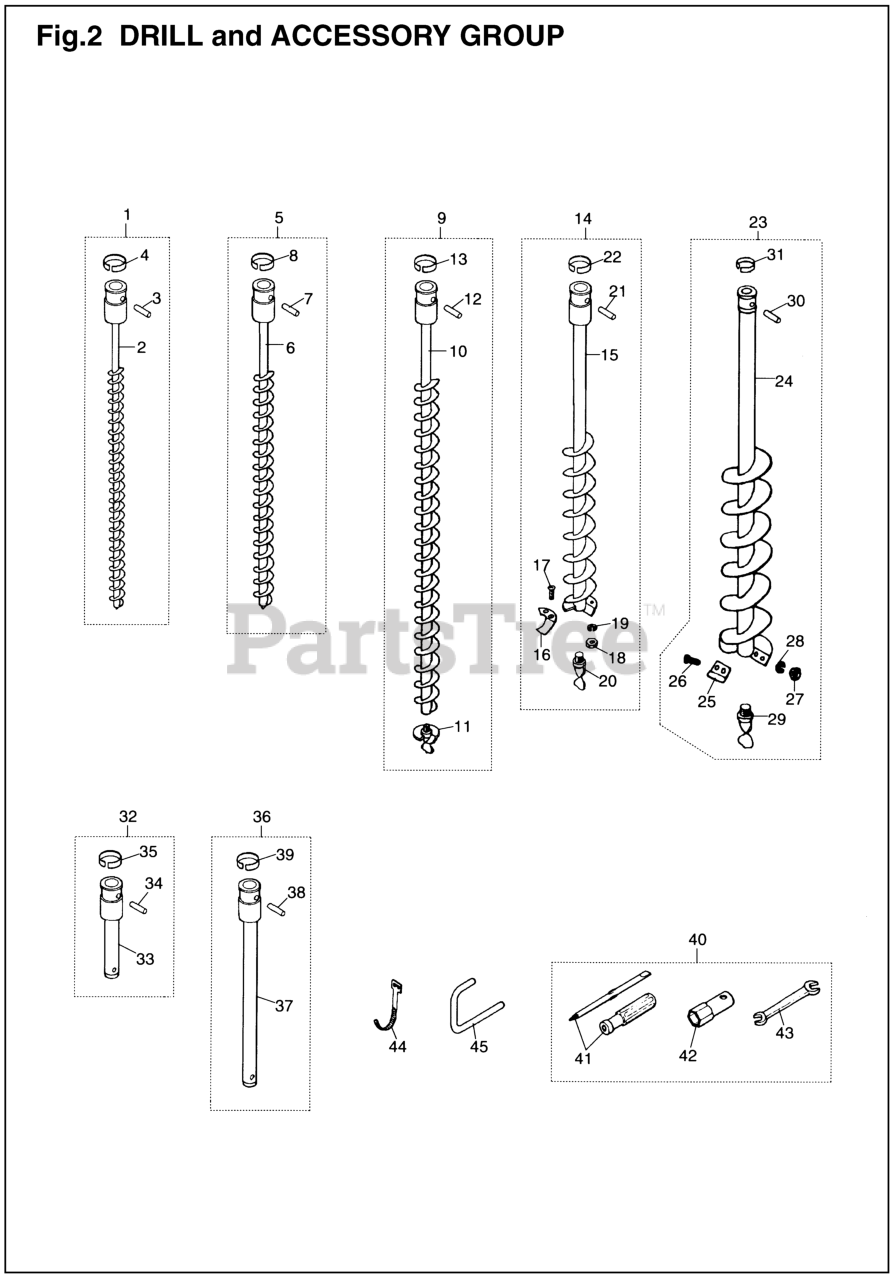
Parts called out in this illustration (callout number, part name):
17	SCREW, M6 x 20
23	DRILL.S90 ASSY
26	SCREW, M6 x 20
40	TOOL SET
44	BAND(KZC)
